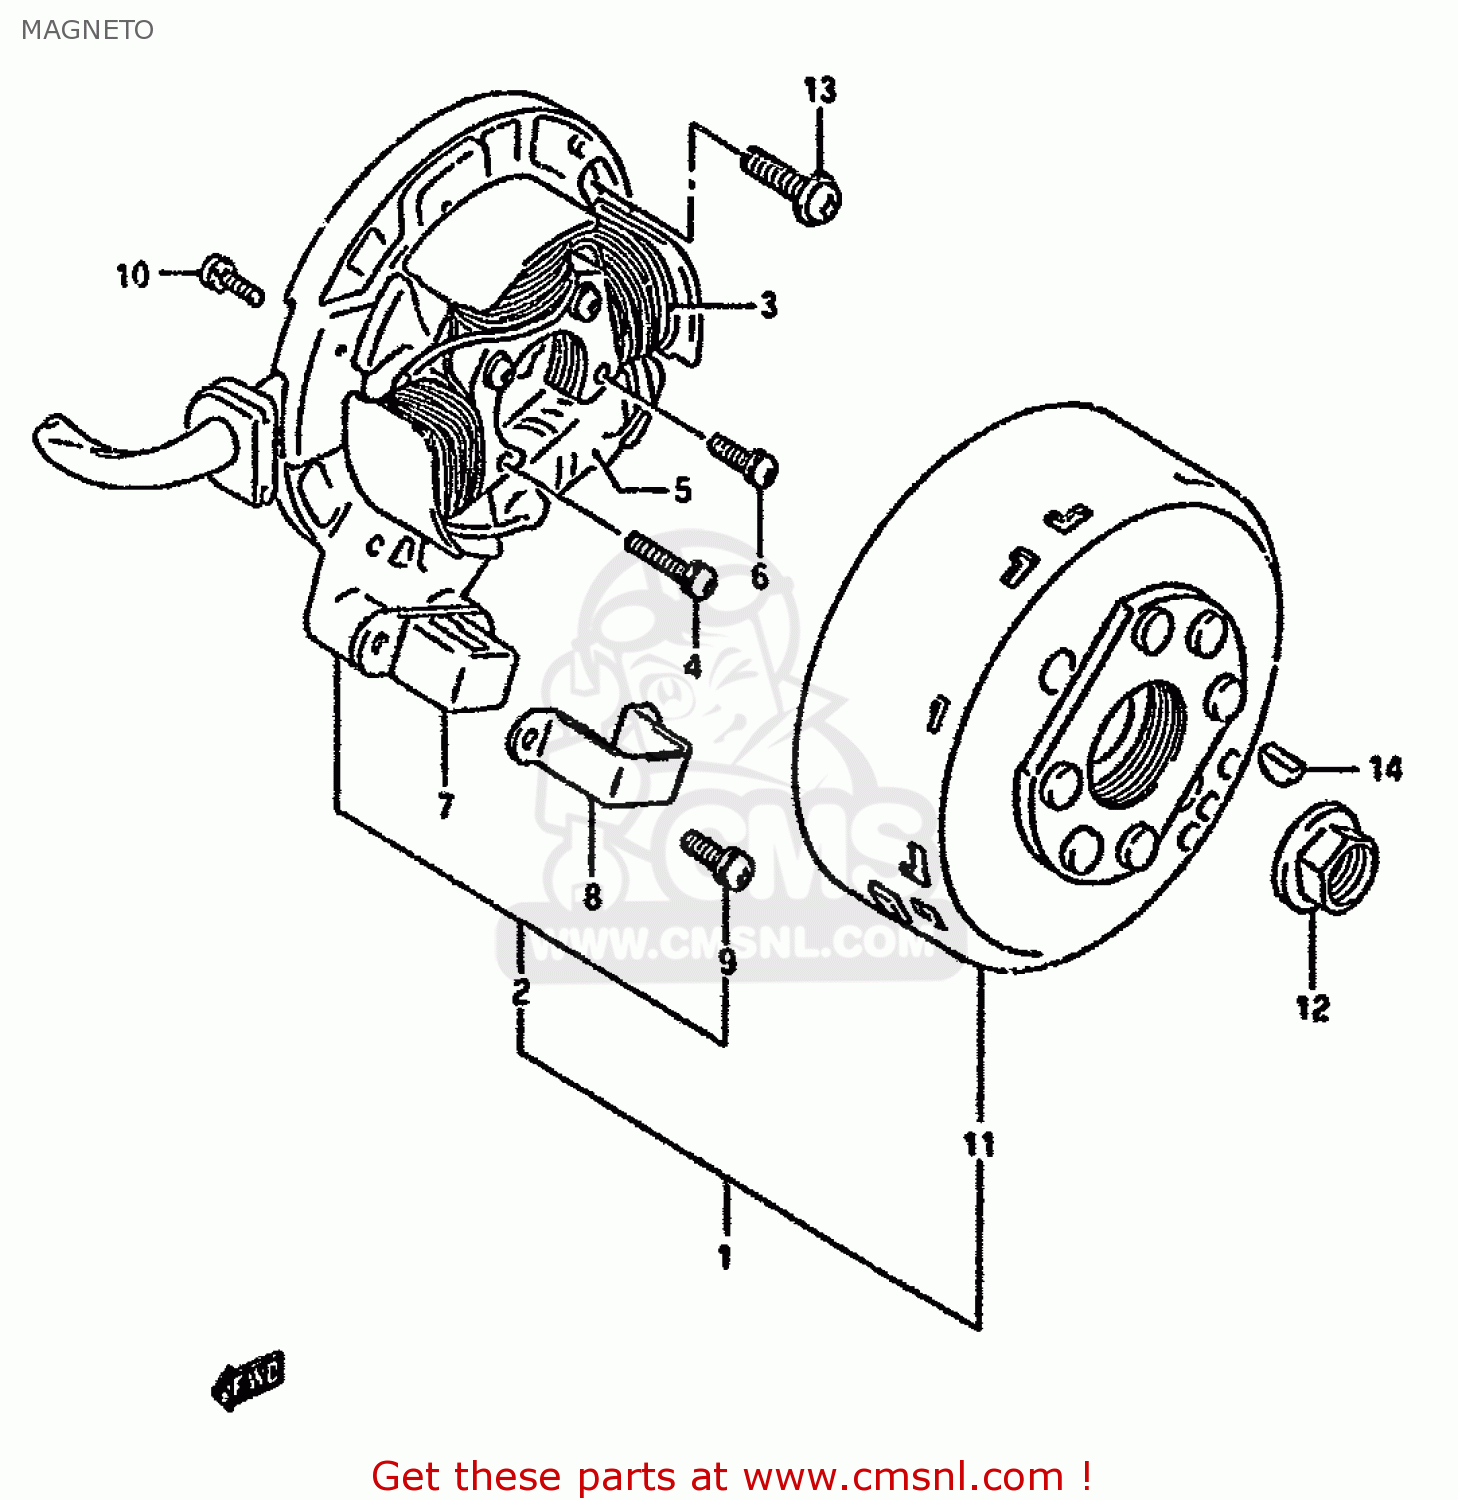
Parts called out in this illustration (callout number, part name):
1	MAGNETO ASSEMBLY
2	STARTER ASSY
3	COIL,LIGHTING
4	SCREW
5	COIL,PRIMARY
6	SCREW
7	COIL,PULSER
8	HOLDER,PICK UP COIL
9	SCREW
10	SCREW
11	ROTOR ASSY
12	NUT
13	SCREW
14	KEY
